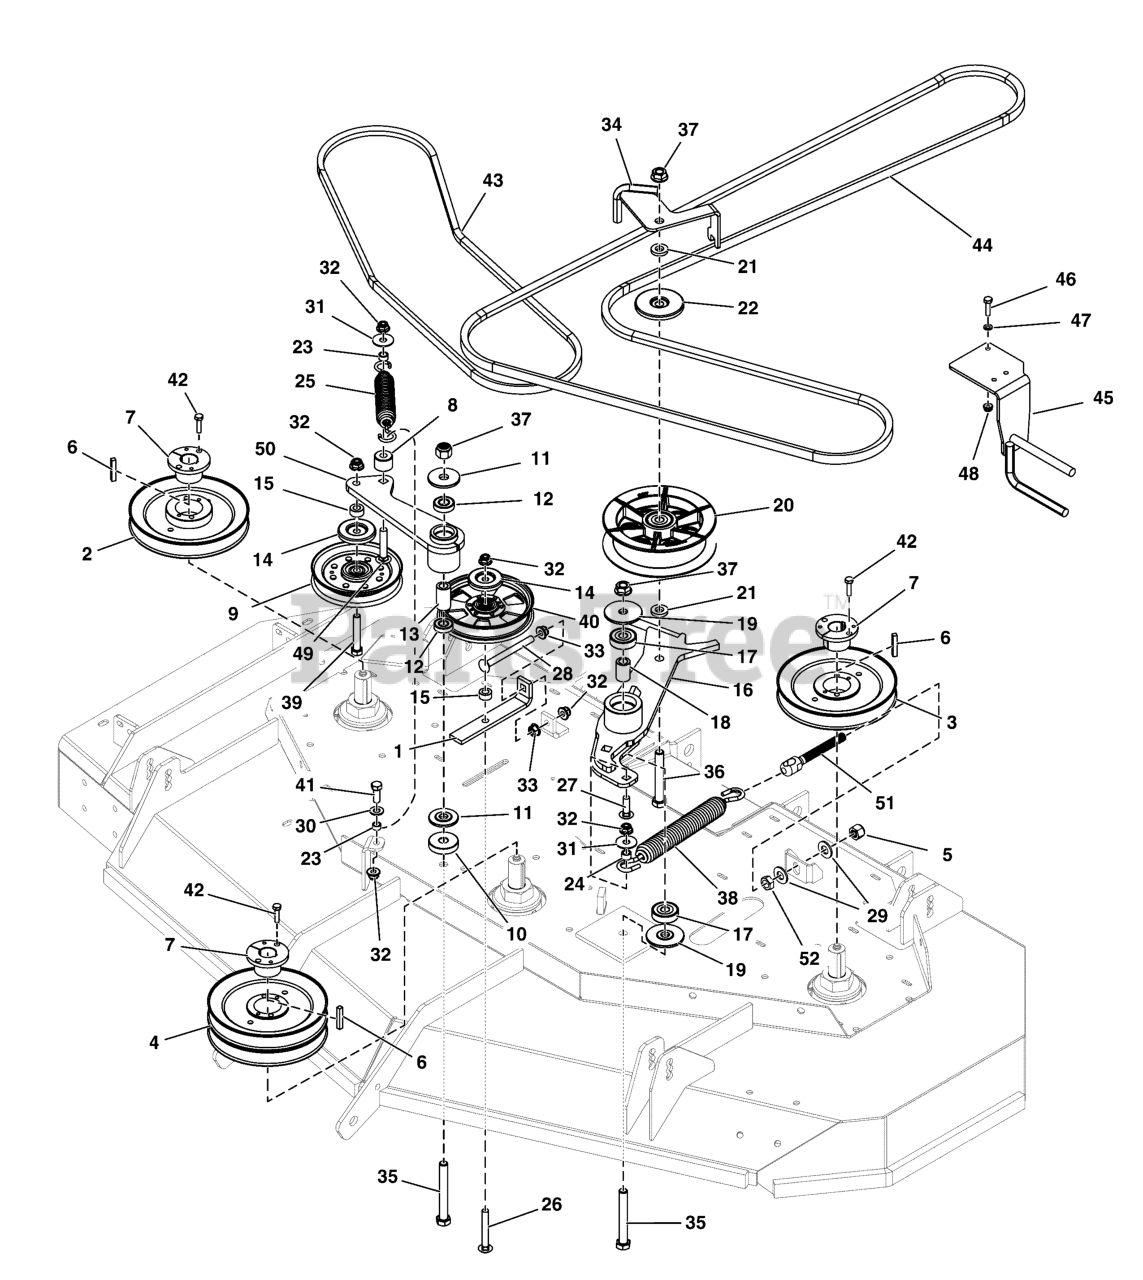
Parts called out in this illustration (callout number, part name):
2	PULLEY
3	PULLEY
4	PULLEY
5	NUT, Hex, Nylon Lock, 1/2-20
6	KEY 1/4 SQ X 1 1/2 LONG
7	BUSHING, TAPERED HUB
8	SPACER, .39 X 1.00 X .75, CZ
9	PULLEY, V-IDLER, 5"OD X 3/8", CZ, TE
11	SPACER, Idler Arm
12	BEARING, Ball
14	SHIELD, PULLEY, 3/8"ID X 2"OD, CZ
16	ARM, Idler
17	BEARING, 6203-1/2", SEALED
18	SPACER, .51 X .75 X 1.22, PM, CZ
19	SPACER, IDLER ARM, 1/2 X 2.25
20	PULLEY, IDLER, 5.50, CI, DBL BEARING
21	SPACER, .52 X 1.00 X .22, PM, CZ
22	SHIELD, PULLEY, 1/2"ID X 2-7/8"OD, CZ
23	SPACER, .38 X .50 X .27, CZ
24	SPACER, .39 X .63 X .375, DOM
25	SPRING, Extension (48" Model - SN: 426 & up)(52: Model - SN: 351 & up)
26	BOLT, 3/8-16 X 2-1/2, CARRIAGE, GD5, CZ
27	BOLT, Carriage, 3/8-16 X 1 1/2, GR5
28	BOLT, 3/8-16 X 4-1/2, CARRIAGE, GD5, CZ
29	WASHER, 1/2
30	WASHER, .406
31	WASHER, Fender, 3/8
32	NUT, Hex Flange, Nylock, 3/8-16
33	NUT, Hex, Serrated Flange, 3/8-16 (S/N 616 & up)
34	GUIDE, Belt
35	BOLT, 1/2-13 X 4 GD5 YZ
36	CAPSCREW, Hex Hd, 1/2-13 x 3-1/2
37	NUT, Hex Flange, 1/2-13
38	SPRING, EXT1.22"ODX10.5"FLX.192"WIRE BLK
39	CAPSCREW, Hex Head, 3/8-16 X 1-3/4
40	PULLEY
41	CAPSCREW, Hex Head, 3/8-16 x 1
42	BOLT, 1/4-20 X 1", GD
43	BELT
44	BELT
45	GUIDE, Belt
46	BOLT, 1/4-20 X 1", GD
47	WASHER, Flat, 1/4
48	NUT, Flange Nylock , 1/4-20
49	BOLT, 3/8-16 X 2, CARRIAGE, GD5, CZ
50	WELD, IDLER ARM, 2 BELT DRIVE - BLK
51	SPRING PULLER, 1/2-20, 6.00
52	NUT, Hex Jam, 1/2-20
